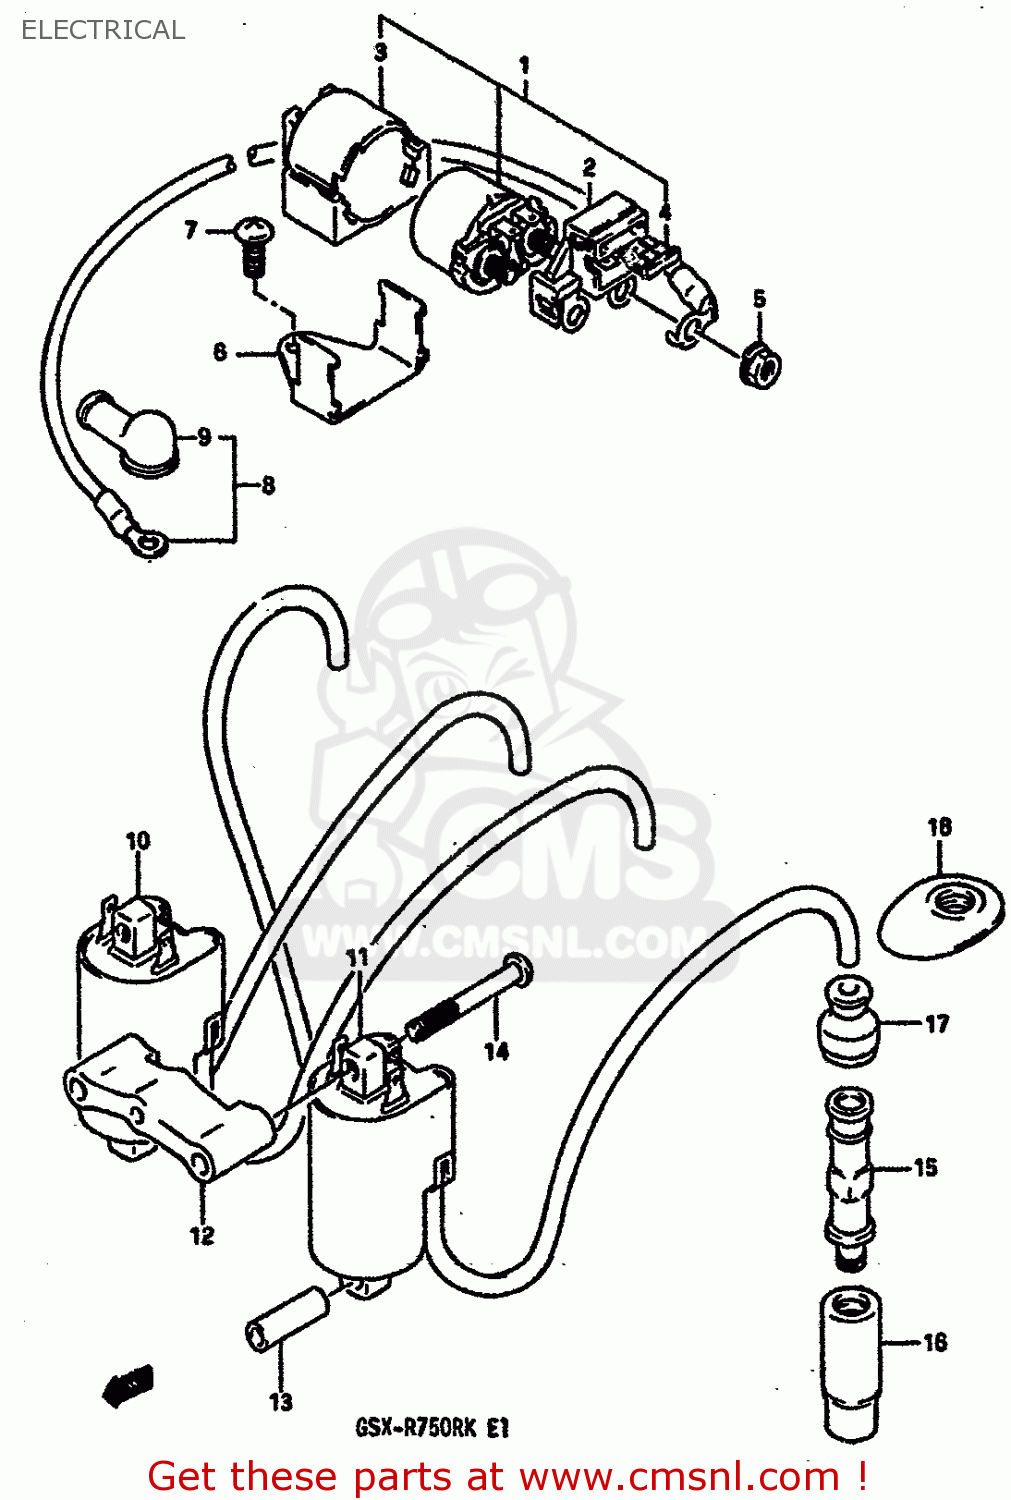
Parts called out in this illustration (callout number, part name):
1	RELAY ASSY,STARTING MOTOR
2	TERMINAL,RELAY
3	BRACKET,STARTING MOTOR RELAY
4	FUSE (30A)
5	NUT
6	BRACKET,STARTING MOTOR RELAY
7	SCREW
8	LEAD WIRE,STARTING MOTOR
9	CAP,STARTER MOTOR TERMINAL
10	COIL ASSEMBLY,IGNITION (1-4)
11	COIL ASSEMBLY,IGNITION (2-3)
12	SPACER,SECOND AIR BRACKET,UPPER
13	SPACER (6.2X10X30)
14	SCREW
15	CAP,SPARK PLUG
16	SEAL,SPARK PLUG
17	SEAL,HIGH TENSION CORD
18	COVER,SPARK PLUG CAP
